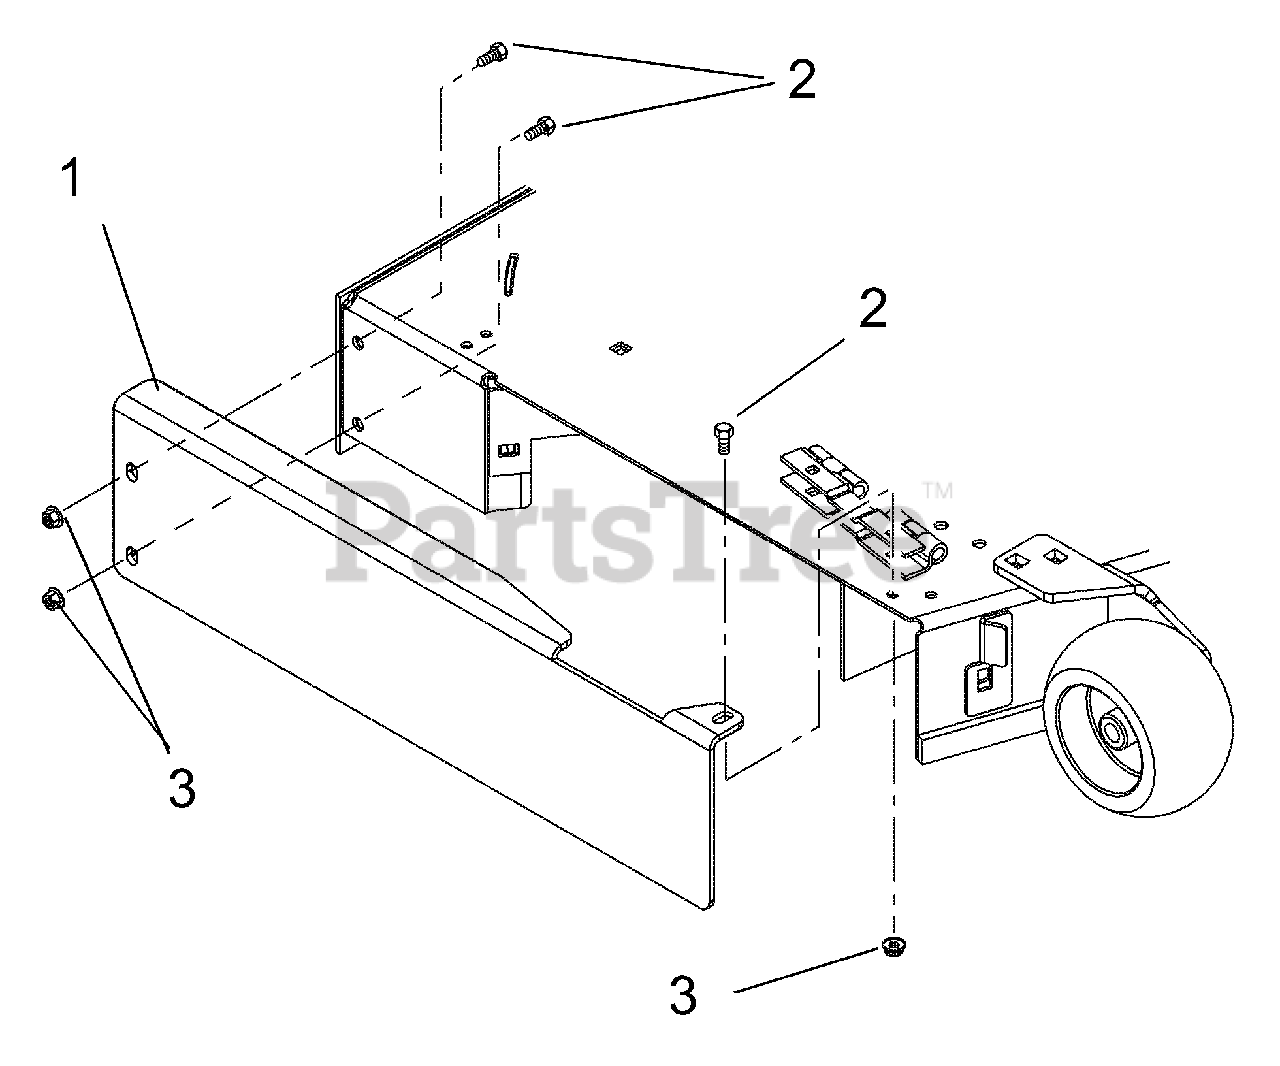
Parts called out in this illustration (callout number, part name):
1	Debris Baffle
2	1/4"-20 x 3/4" Hex Bolt
3	1/4"-20 Top Locking Flange Nut
